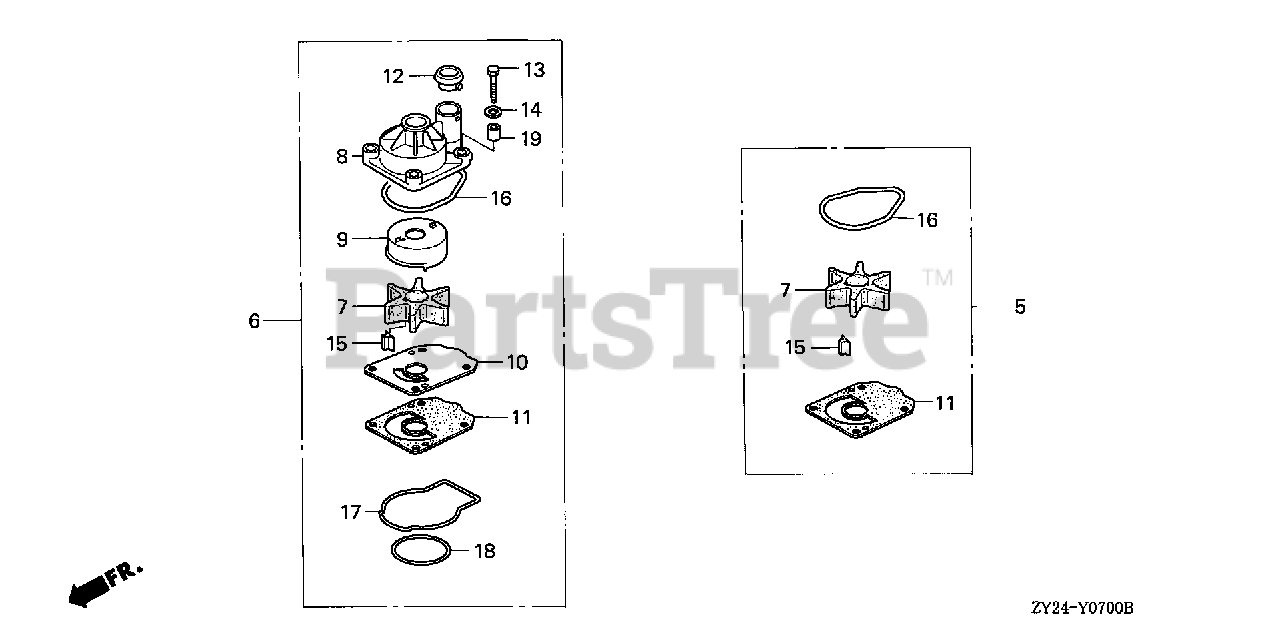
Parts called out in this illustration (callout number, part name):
5	PUMP KIT, IMPELLER
6	PUMP KIT, IMPELLER
7	IMPELLER, PUMP
8	HOUSING, IMPELLER
9	LINER, PUMP
10	COVER, IMPELLER
11	GASKET B, IMPELLER
12	RING, WATER TUBE SEAL
13	BOLT, HEX. (8X60)
14	WASHER (8MM)
15	KEY, WOODRUFF
16	O-RING, WATER PUMP
17	O-RING, WATER PUMP HOUSING
18	O-RING (69.1X2.4)
19	COLLAR, DISTANCE
